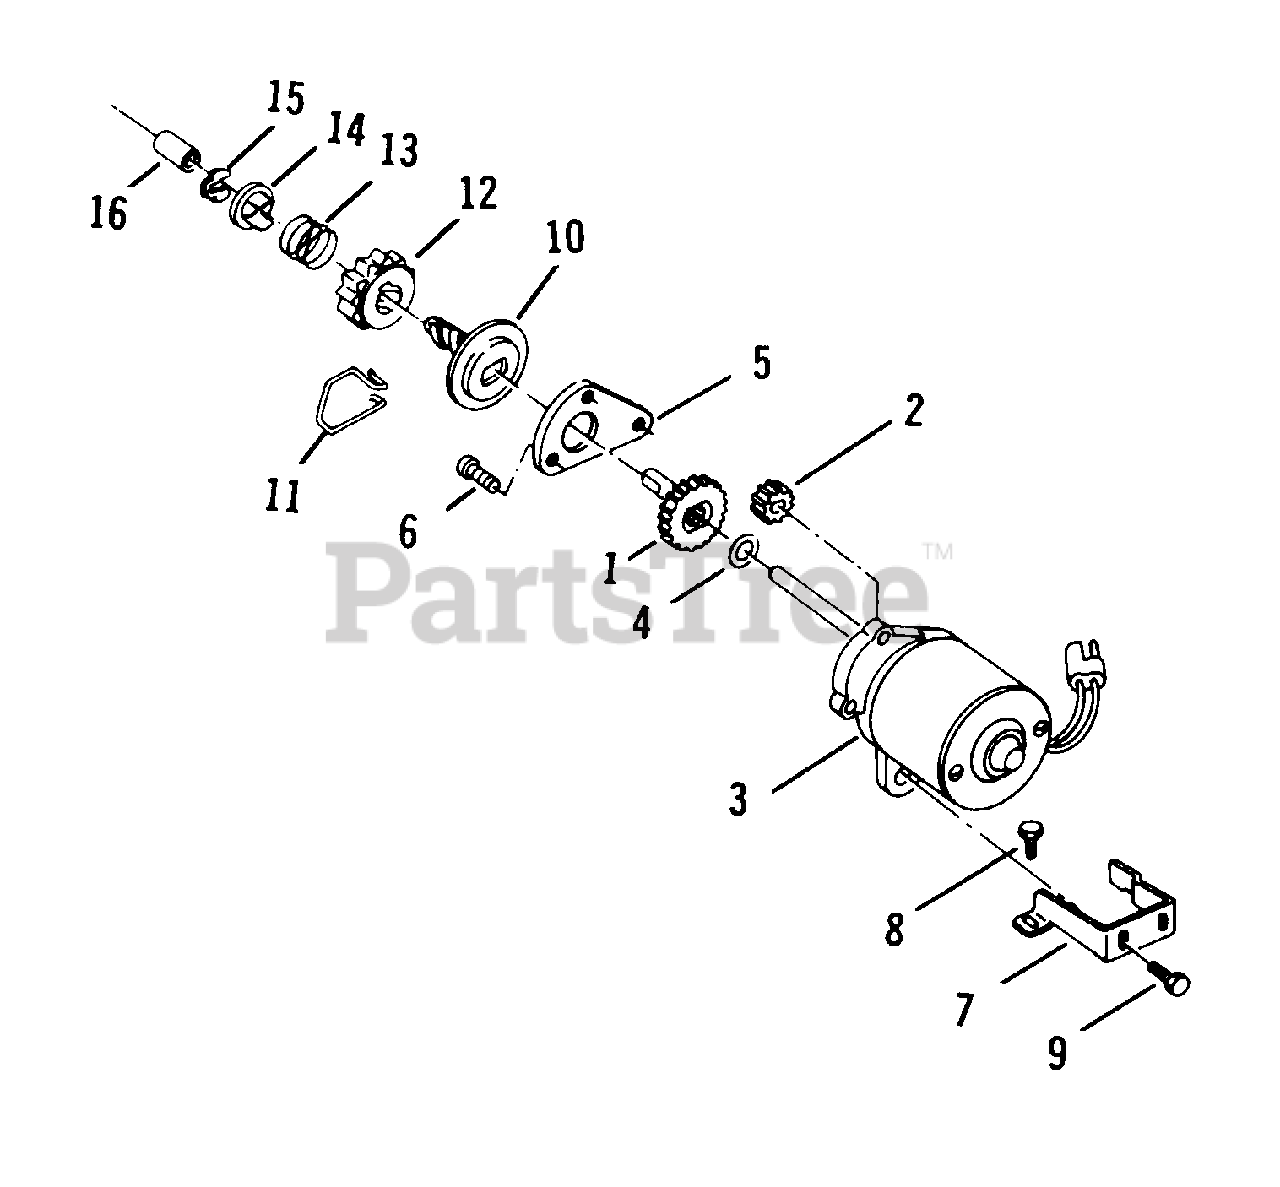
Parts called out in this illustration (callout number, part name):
1	Gear-Driven
2	Pinion-Motor Shaft
3	Motor Housing and Pin Assembly
4	Washer
5	Plate-Gear Cover
6	Screw
7	Bracket-Starter Mounting
8	Screw
9	Screw
10	Pinion, Spring and Clutch Assembly
11	Spring-Drag
12	Pinion
13	Spring-Pinion Return
14	Washer-Pinion Stop
15	Retaining Ring
16	Sleeve
